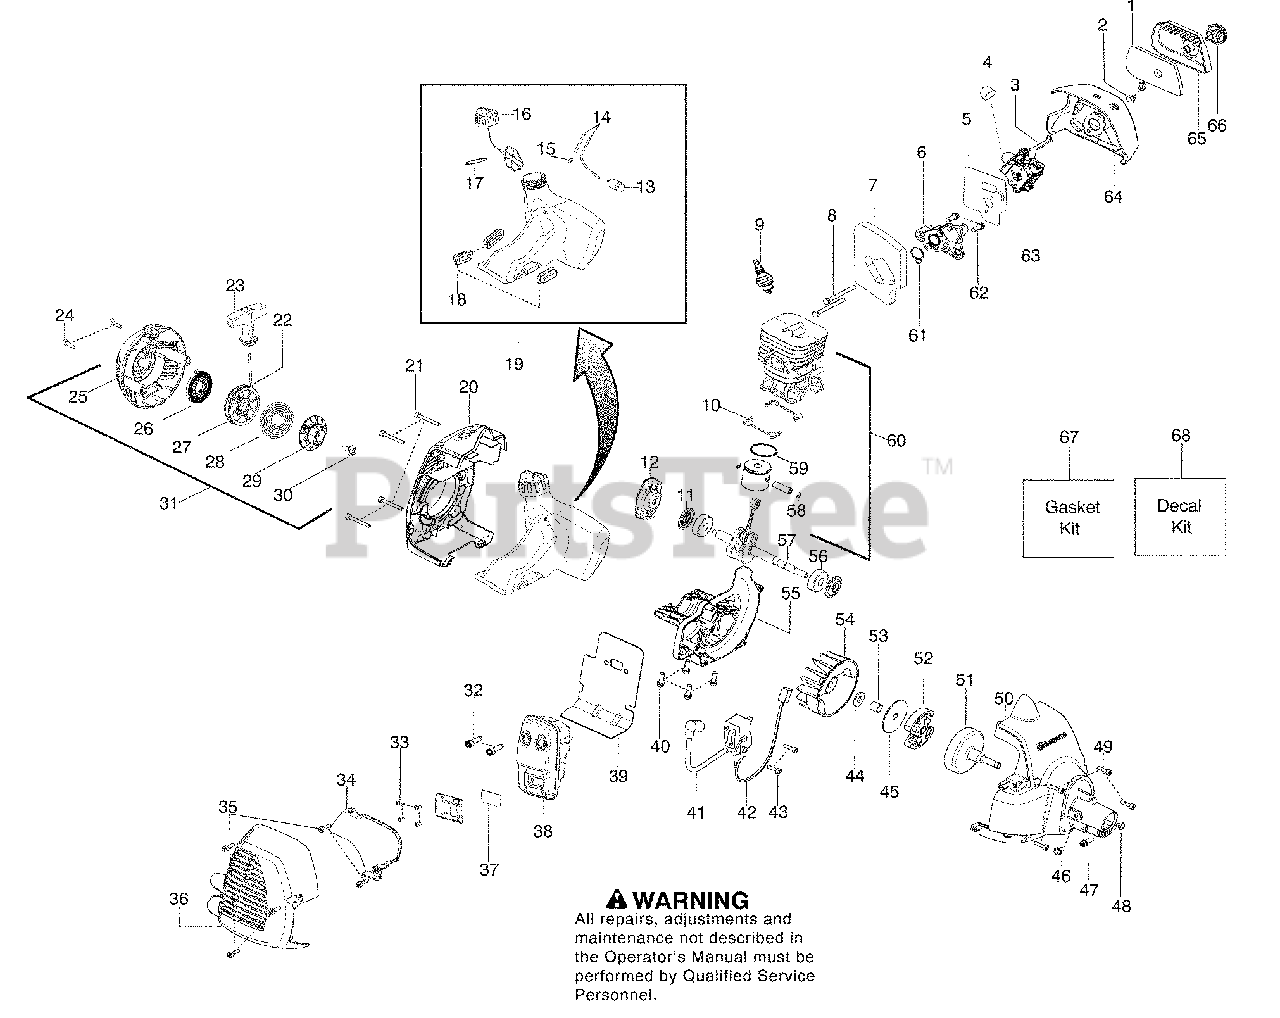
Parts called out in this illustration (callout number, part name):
2	Nut-Carb. Screw
3	Lever - Choke
4	Bulb-Purge
5	Kit-Carb. Gasket
6	Adaptor-Carb.
7	Foam-Gasket (kit)
9	Plug-Spark (RCJ-8Y)
10	Seal-Cylinder (kit)
11	Seal-Crankshaft (kit)
12	Assy-Starter Pawl
13	Assy-Fuel Filter
14	Kit-Fuel Line(Incl. 15)
15	Fitting-Fuel Line
16	Assy-Cap w/ret.
17	O-ring-Fuel Cap (kit)
18	Isolator-Fuel Tank
19	Kit-Fuel Tank Assy.
20	Shroud-Rear
22	Kit-Rope
23	Handle-Starter
25	Starter Hsg. w/eyelet
26	Kit-Spring
27	Kit-Starter Pulley
28	Spring - Driver
29	Pulley-Driver
31	Assy-Starter Hsg.
32	Bolt-Muffler
33	Screw
34	Shield-Heat
36	Guard-Muffler
37	Kit-Spark Arrestor
38	Kit-Muffler
39	Gasket-Paper met.(kit)
42	Assy-Leadwire
45	Washer-Clutch
50	Assy-Fan Housing
51	Assy-Clutch Drum
52	Assy - Clutch
55	Crankcase
57	Assy-Crankshaft
58	Retainer-Piston Pin
59	Ring-Piston
60	Kit-Piston/Cyl.
61	Kit-Gasket (adaptor seal)
63	Kit-Carb.
64	Airbox
65	Cover-Air Box
67	Kit-Gasket
